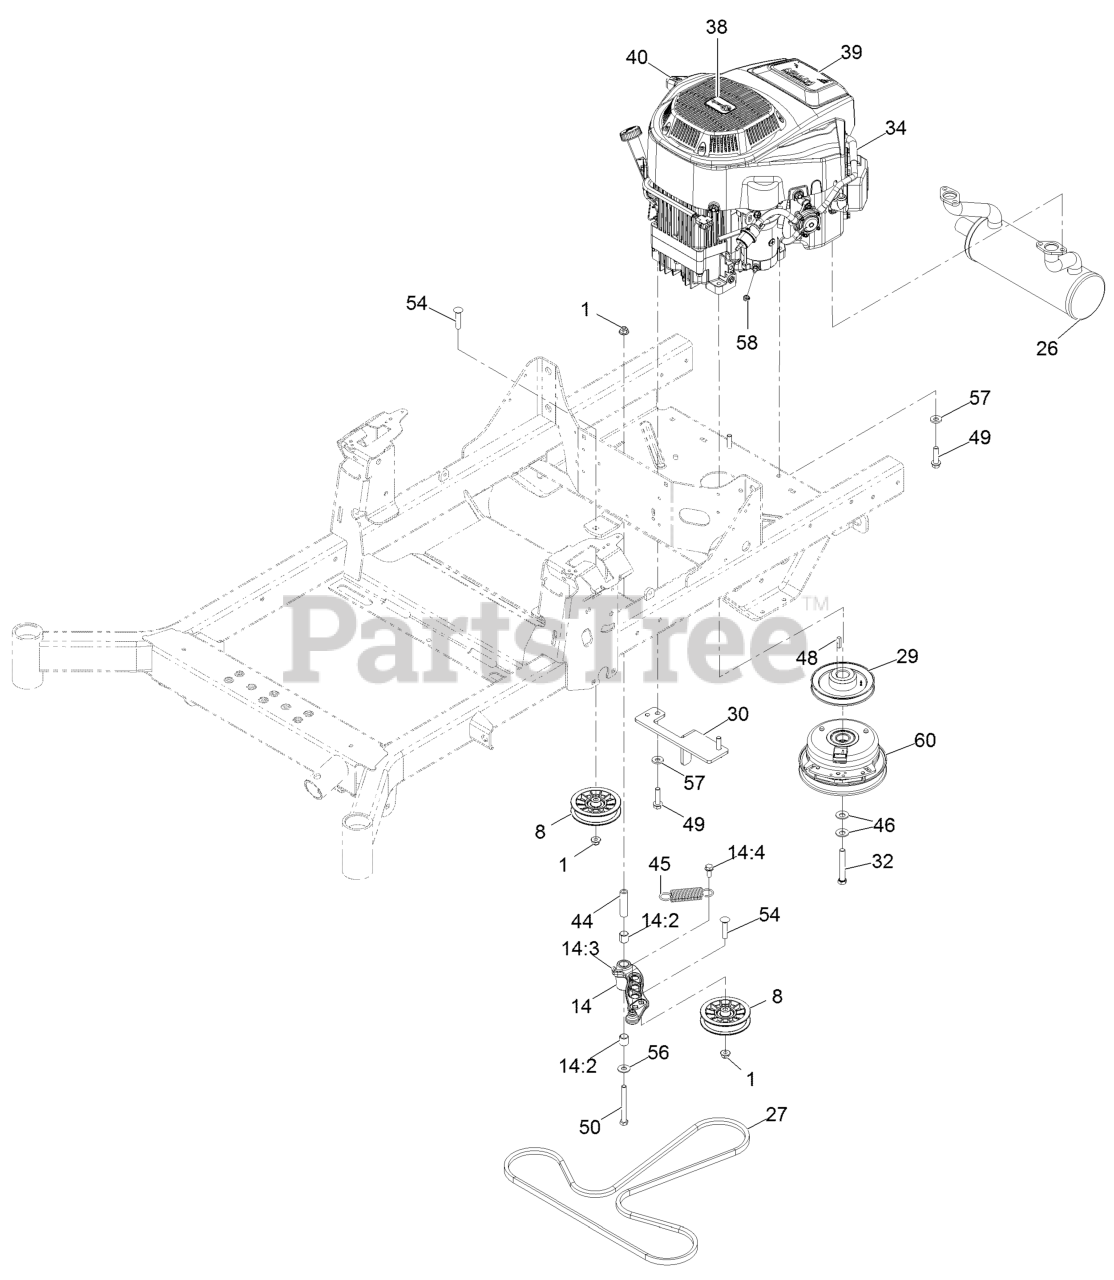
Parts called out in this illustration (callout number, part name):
1	Nut-Nyloc 3/8-16 Flg
8	Pulley-Flat
14	Idler Arm ASM
14:2	Sleeve-Bearing
14:3	Zerk-90deg 1/4-28
14:4	Screw-HWH 5/16-18 X 3/4 Tf
26	Muffler
27	Belt-V
29	Sheave-Engine
30	Anchor-Clutch
32	Screw-HH 7/16-20 X 3 W/Loctite
34	Engine-2P77F
39	Decal-708Cc V-Twin Engine
40	Decal-Drain, Oil
44	Bushing-Pivot, Idler
45	Spring-Extension
46	Washer-Spring Disc 7/16
48	Key-Machine 1/4 X 1/4 X 1
49	Screw-HWH 3/8-16 X 1 1/2 Taptite
50	Screw-HH 3/8-16 X 3 1/2
54	Bolt-Carriage 3/8-16 X 1 3/4
56	Washer-3/8 Std
57	Washer-Spring Disc 3/8
58	Nut-Hex M6-1 Flg
60	Clutch - 1.00 HD
